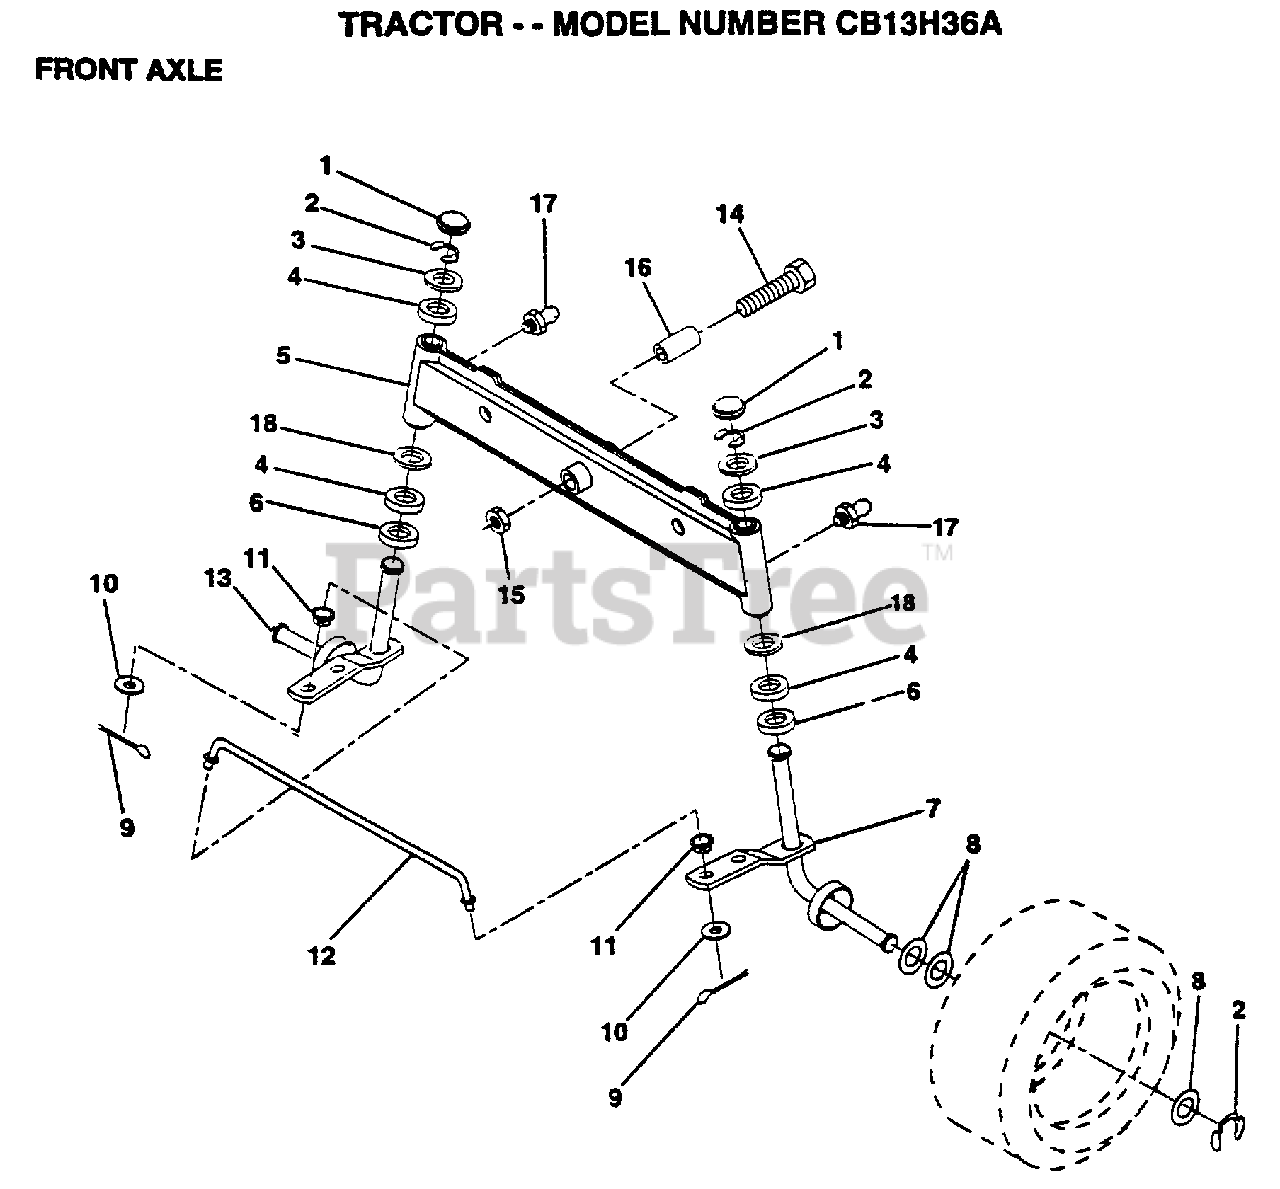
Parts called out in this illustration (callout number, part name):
1	CAP
2	RING
3	WASHER
4	COL. SRTG. BEAR.
5	AXLE ASM FRONT
6	WASHER .T
7	SPINDLE ASM RH
8	WASHER
9	COTTER PIN
10	WASHER
11	BUSHING.DRAGLINK
12	TIE ROD
13	SPINDLE ASM LH
14	BOLT HEX 5/8-11
15	"NUT-LOC,FLANGE LT"
16	BEARING
17	ZERK M
18	WASHER
